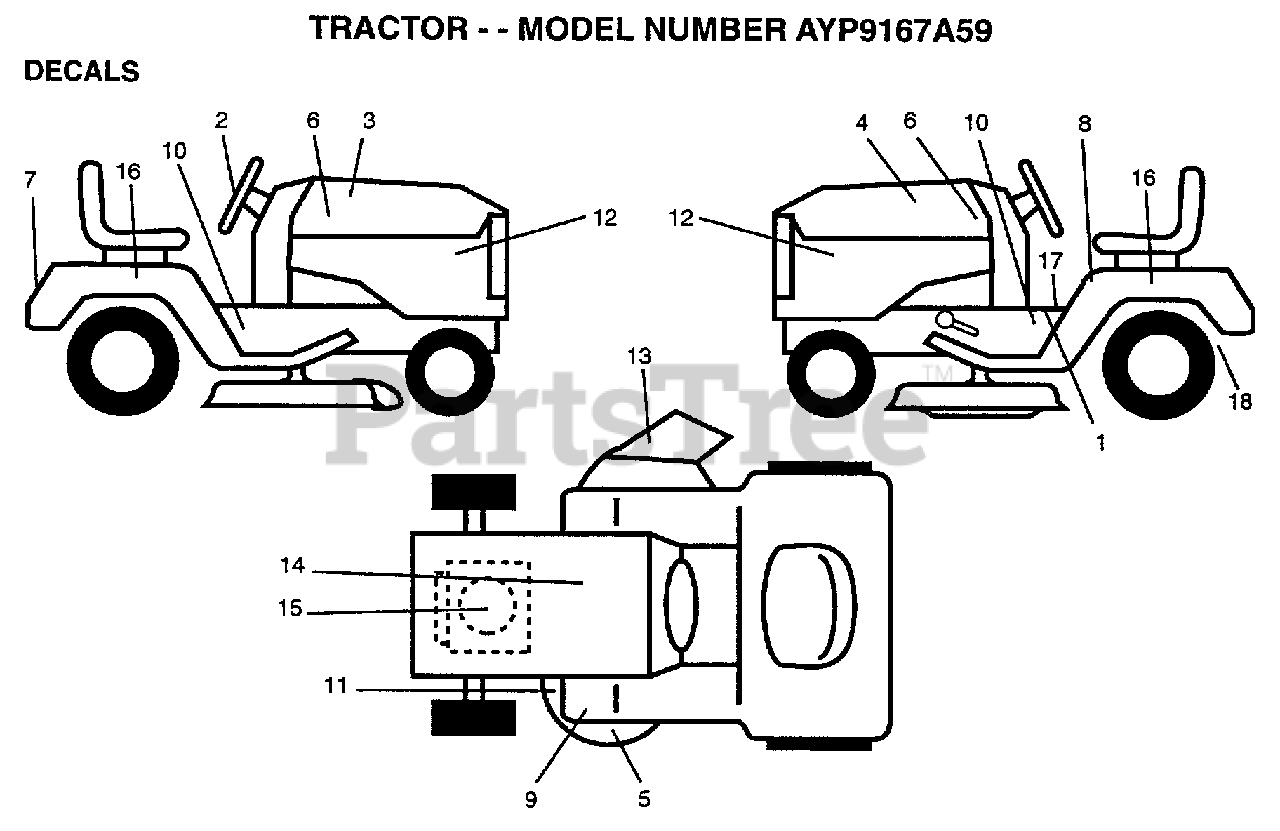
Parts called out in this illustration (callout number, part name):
2	DECAL STEER WHL
3	DECAL HOOD RH
4	DECAL HOOD LH
5	DECAL DECK WIZ +
6	NAMEPLATE.HD.WIZA
8	DECAL
10	"DECAL.CHASSIS.42"""
11	DECAL
12	DECAL.PNL.SIDE.VG
13	DECAL DECK MULCH
14	DECAL.BATRY.3-3908
15	DECAL.ENG.805720
16	DECAL.FENDER.WIZ
17	DECAL SADLE HYDRO
18	DECAL DRAWBAR LH
